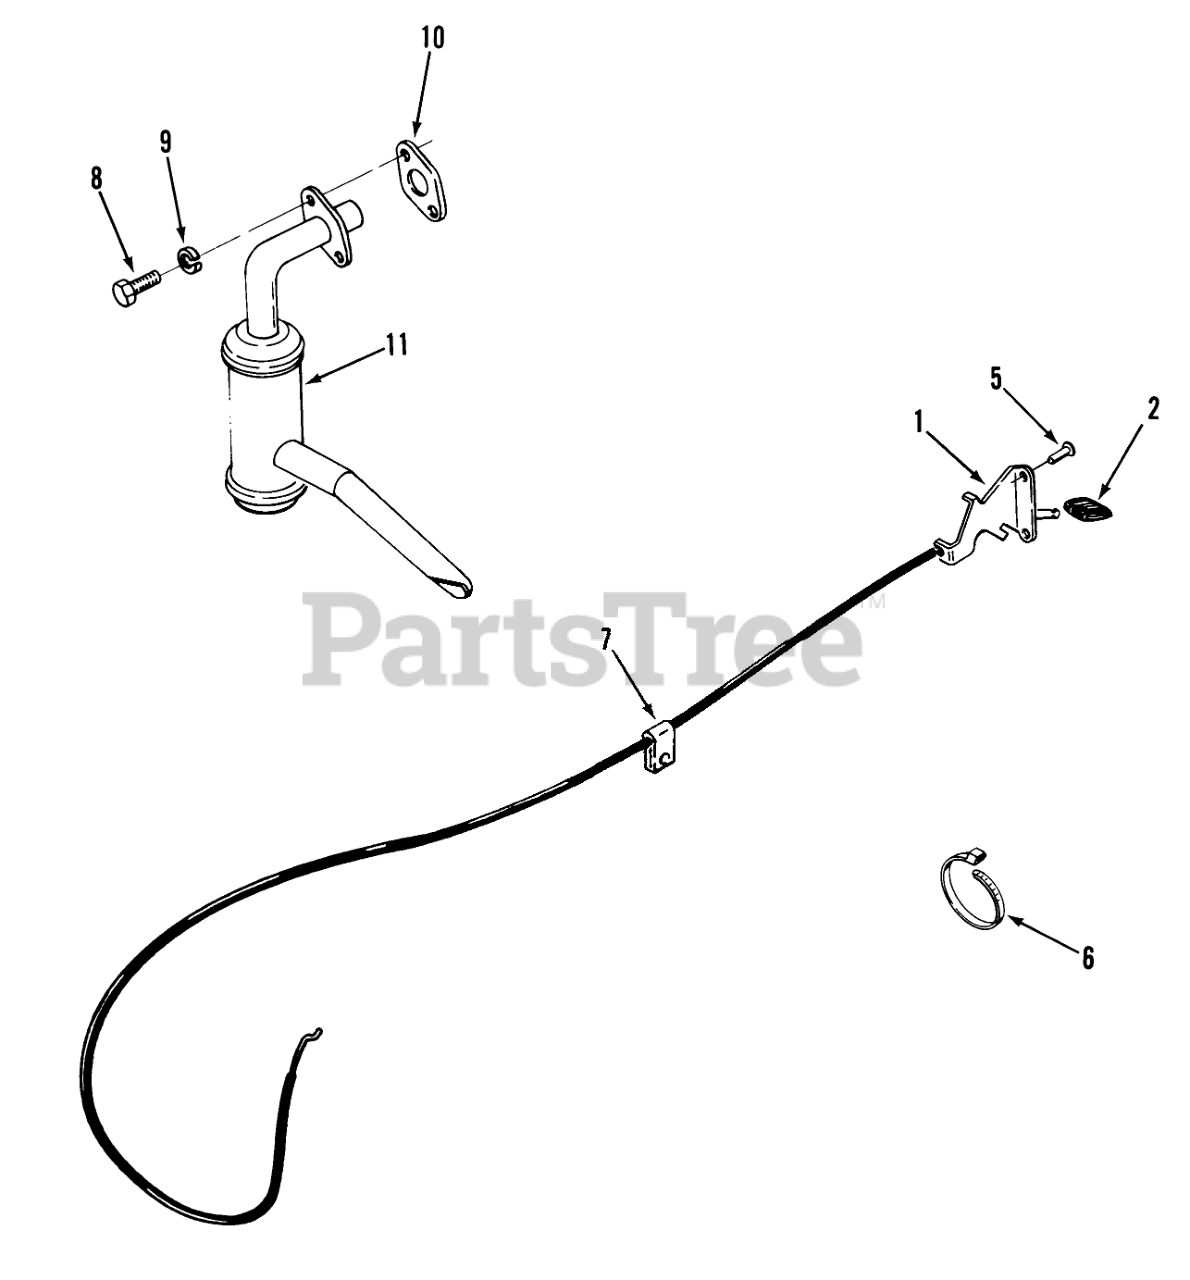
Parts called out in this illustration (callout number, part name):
1	CHOKE & THROTTLE CON
2	KNOB-THROTTLE
5	Pip Rivet
6	PLASTIC TIE
7	THROTTLE CONTROL CLP
8	Bolt
9	Lockwasher
10	Gasket Exhaust
11	Muffler
